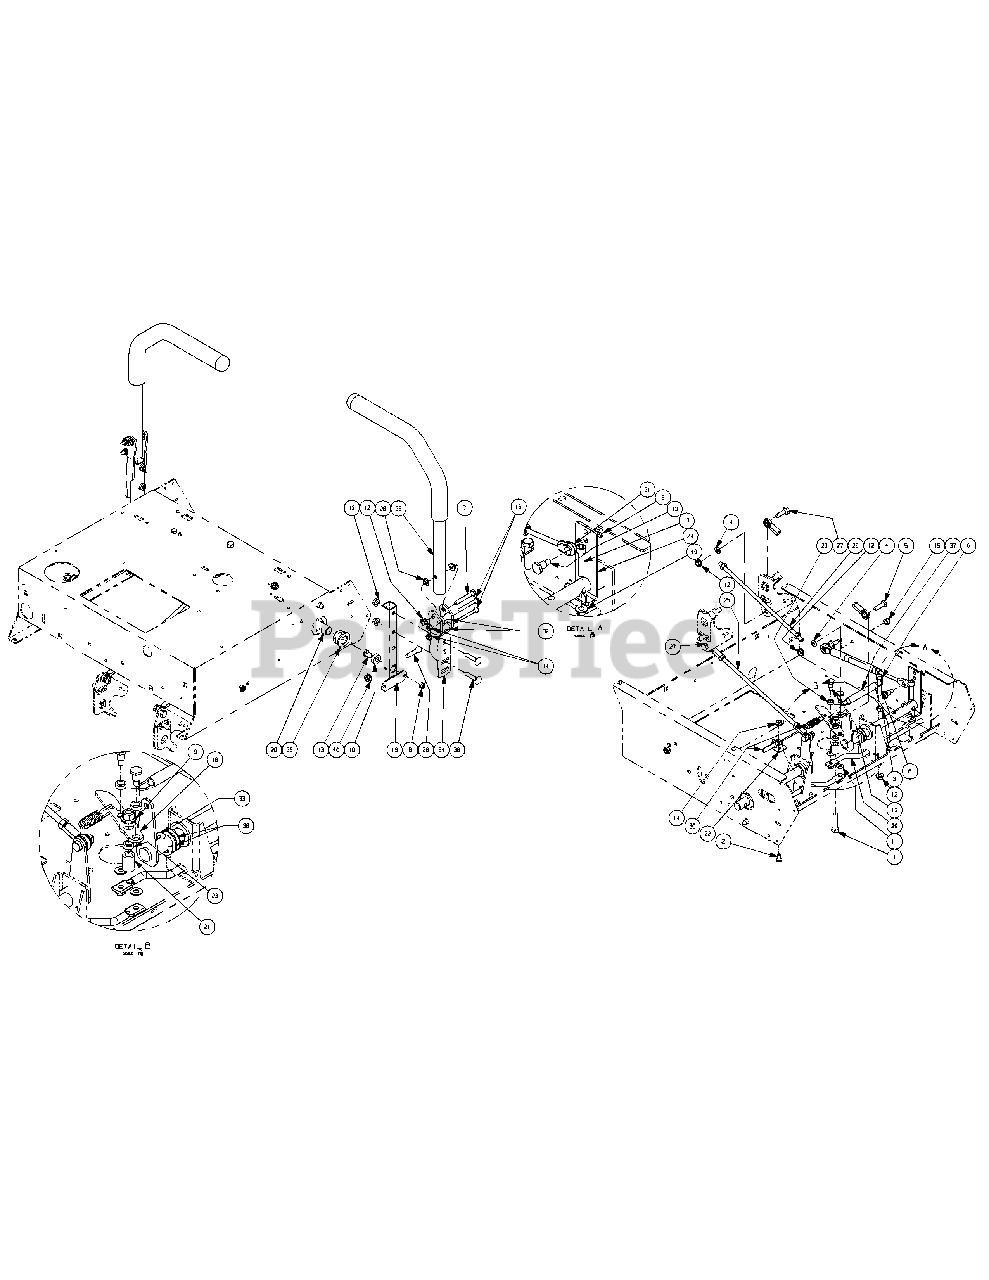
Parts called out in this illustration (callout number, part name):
1	Hex Cap Screw, 3/8-16 x 1-1/2
2	Hex Cap Screw, 1/4-20 x 1/2
3	Hex Nut, 5/16-18
4	Flat Washer, 5/16
5	Hex Head Cap Screw, 5/16-18 x 1.00
6	Hex Cap Screw, 5/16-18 x 1-1/2
7	Hex Cap Screw, 5/16-18 x 2.00
8	Nut, 1/4-28, SS, Nylon Insert
9	Nut, Flange Lock, 3/8-16
10	Control Rod Spacer
11	Flat Washer, 1.4 x .630 x .0515
12	Nut, 5/16-18, Lock
13	Shoulder Screw, 1/4-28
14	Nut, 1/4-20, Hex Flange Lock Nut
15	Nut, Hex, Center Lock, M8
16	Hex Cap Screw, 1/4-20 x 2.00
17	Capscrew, 5/16-18 x 1.50, Socket Head
18	Brake Lever Plate
19	Pivot Bracket Weldment
20	Steering Input Shaft Assembly
21	Spacer, .385 ID x .625 OD x .869
22	Brake Cable Mounting Bracket
23	Spacer, .380 x .563 x .196
24	Damper Mounting Bracket
25	Steering Link Rod
26	Socket Head Capscrew, 5/16-18 x 1.25
27	Shoulder Bolt, .4375 x .1345 x 1.00
28	Bushing, .310 x .172 x .688 x .06
29	Control Lock Rod
30	Control Cable Lock Out
31	Cylinder Return to Neutral
32	Spacer, .25 ID x .38 OD x 1.13
33	Retainer Ring, E-Clip
34	Lapbar Pivot Bracket
35	Lapbar Assembly includes:
36	Carriage Bolt, 5/16-18 x 1.50
37	Extension SPring, .53 OD x 4.7
38	Flat Washer, .793 ID x 1.24 OD x .060
39	Hex Flange Bearing, .752 ID
40	Nylock Nut, 5/16-18
